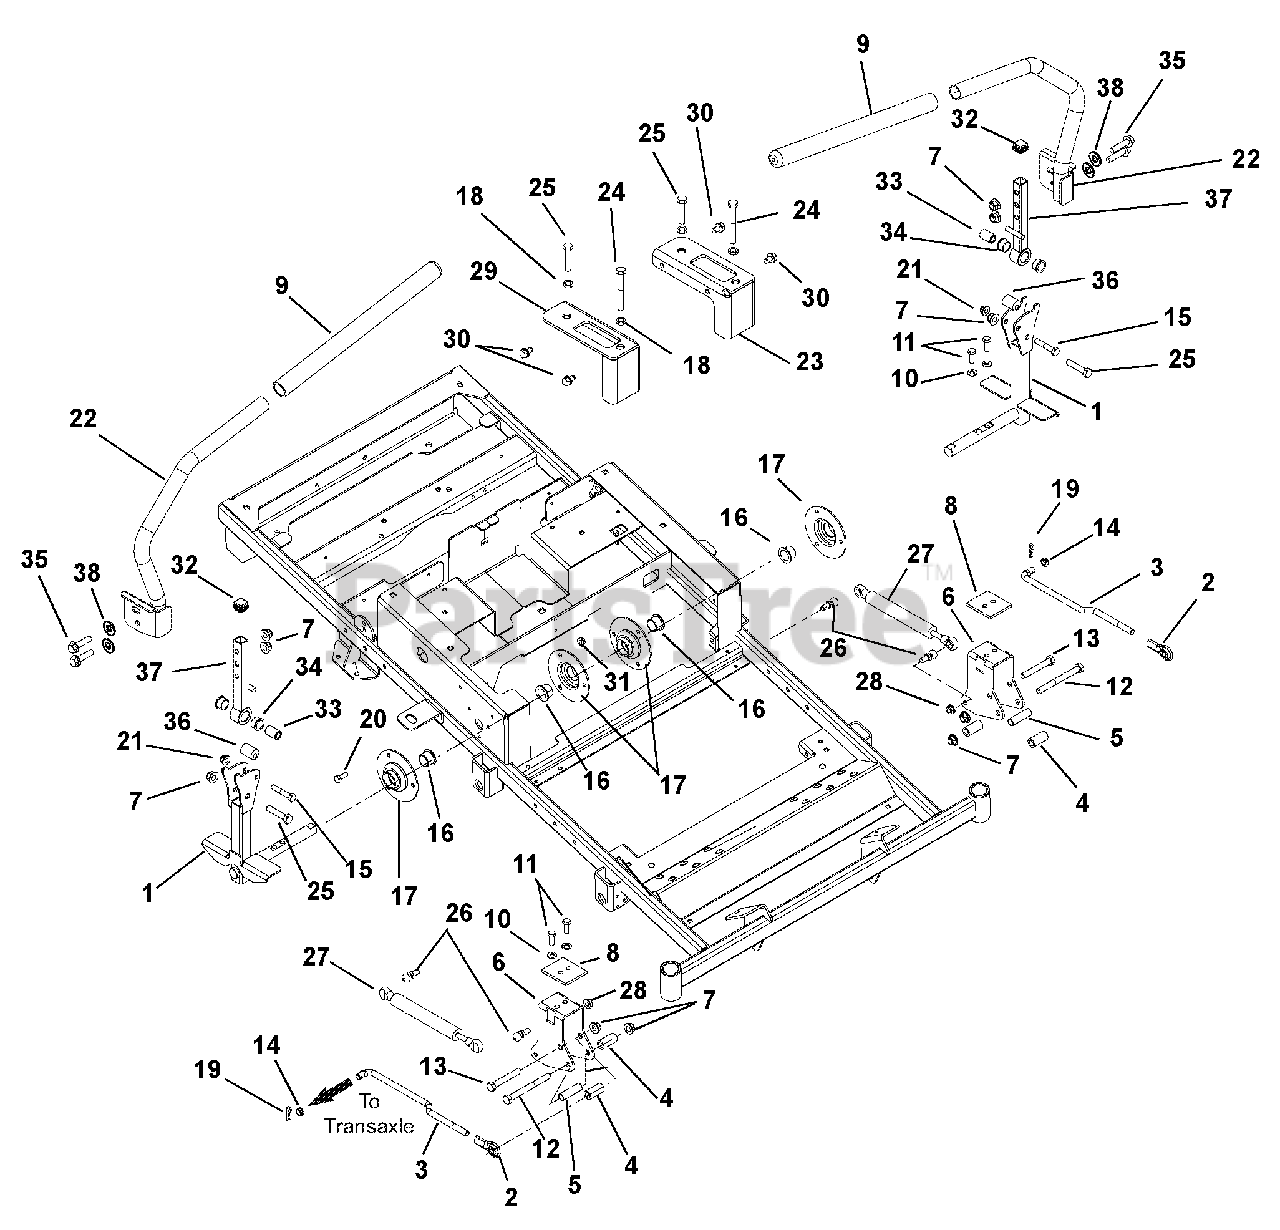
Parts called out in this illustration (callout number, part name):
1	WMT, CONTROL ARM
2	ROD END, .38 RH
3	LINK, TRANSMISSION
4	BSHG, SPCR .390X.625X1.25 PM
5	SPACER, STEERING
6	BRKT, STEERING
7	@NUT-LK-NYL-FLG .38-16 YWZC
8	PLATE, STEERING REINFORCING
9	GRIP, HANDLEBAR 15" FOAM
10	@WSHR-LK .31X.078 REG YWZC
11	BLT-HEX .31-18X1.00 GR8 YWZC
12	@BLT-HEX .38-16X3.75 GR5 YWZC
13	@BLT-HEX .38-16X2.50 GR5 YWZC
14	BUSHING, POLYLINER-.38 SNAPIN
15	@BLT-HEX .31-18X1.75 GR5 YWZC
16	BSHG-FLG .750X1.000X.625X1.250
17	BEARING FLANGE
18	NUT-HEX-JAM .375-16 YWZC
19	PIN-HAIR INT .08X.18X1.18 YWZC
20	@BLT-HEX .25-20X.75 GR5 YWZC
21	@NUT-LK-NYL-FLG .31-18 YWZC
22	WMT, STEERING HANDLE RH
22	WMT, STEERING HANDLE LH
23	BRACKET, LH SPEED CONTROL
24	BLT-HEX .38-16X3.00 GR5 FTH YZ
25	BLT-HEX .375-16X1.750 FTD YWZC
26	STUD- BALL
27	DAMPER, CONTROL
28	@NUT-LK-TOP-FLG .31-18 YWZC
29	BRACKET, RH SPEED CONTROL
30	@SCR-TAP .31-18X.50 HWH TR YWZ
31	@NUT-LK-TOP-FLG .25-20 YWZC
32	CAP PLUG, SQ 3/4-14-20 RIBBED
33	SPACER, .375X.625X.970 (PM)
34	BSHG-FLG, .625X.75X.450X.875
35	BLT-SERHFWH .375-16X1.25 YWZC
36	BSHG, ECCENTRIC .328X.750X.970
37	WMT, UPPER CONTROL ARM
38	@WSHR-FL-STL.406X.812X.065 YWZ
